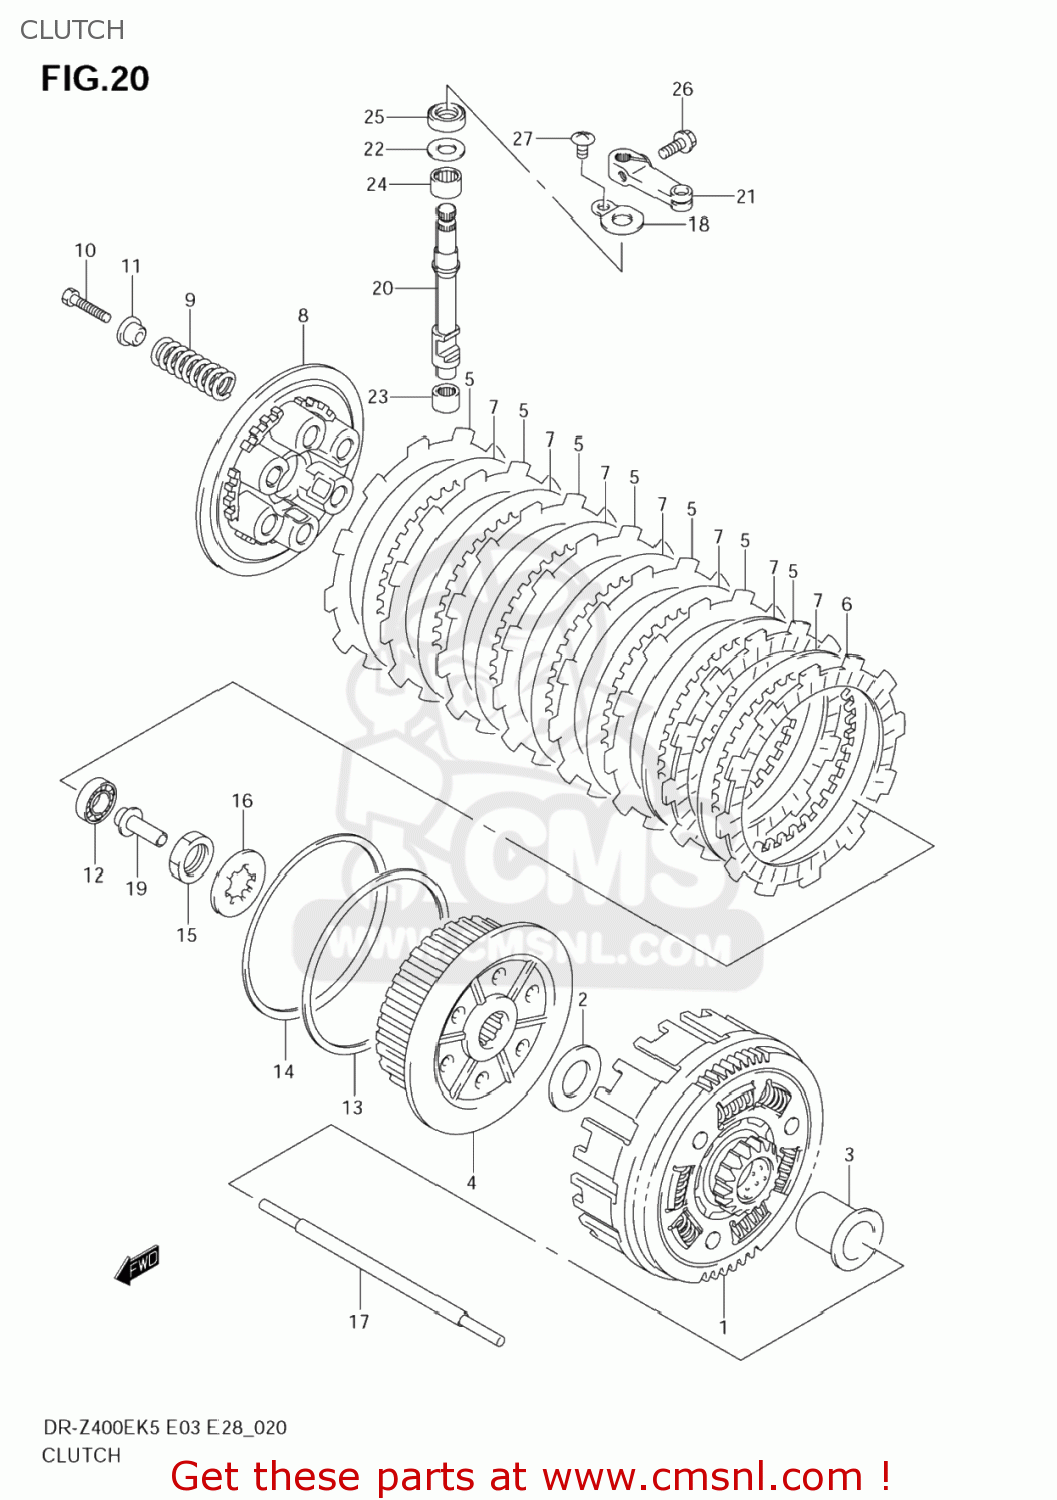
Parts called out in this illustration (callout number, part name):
1	GEAR ASSY,PRI DRIVEN
2	WASHER
3	SPACER,PRIMARY DRIVEN GEAR
4	HUB,CLUTCH SLEEVE
5	PLATE,CLUTCH DRIVE NO.1 (NAS)
6	PLATE,CLUTCH DRIVE NO.2 (NAS)
7	PLATE,CLUTCH DRIVEN (NAS)
8	DISC,CLUTCH PRESSURE
9	SPRING,CLUTCH
10	BOLT
11	WASHER
12	BEARING(12X28X8)
13	WASHER(112X122X1)
14	WASHER
15	NUT
16	WASHER,LOCK
17	ROD,CLUTCH PUSH
18	RETAINER,CL RLSE OIL SEAL
19	PIECE,CL PUSH
20	CAMSHAFT,CLUTCH RELEASE
21	ARM,CLUTCH RELEASE
22	SHIM(10X20X1)
23	BEARING(10X14X10)
24	BEARING(12X16X10)
25	SEAL,OIL(10X20X6)
26	BOLT
27	SCREW 6X10
